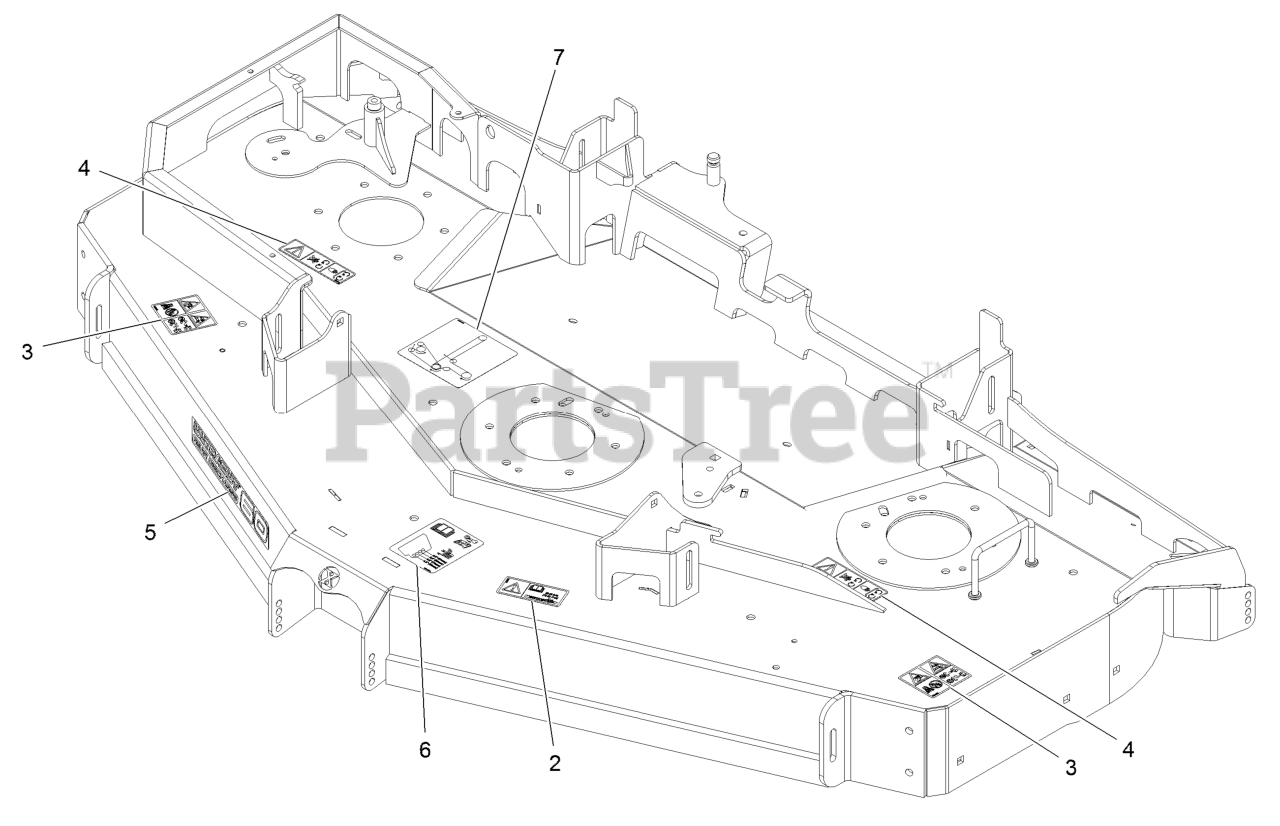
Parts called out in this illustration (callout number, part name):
2	DECAL-BOLT TORQUE
3	DECAL-DANGER, THROWN OBJECT
4	DECAL-COVER, MISSING
5	Decal, 60Rd
6	DECAL-ROLLER, ANTI-SCALP
7	DECAL-ROUTING, BELT
